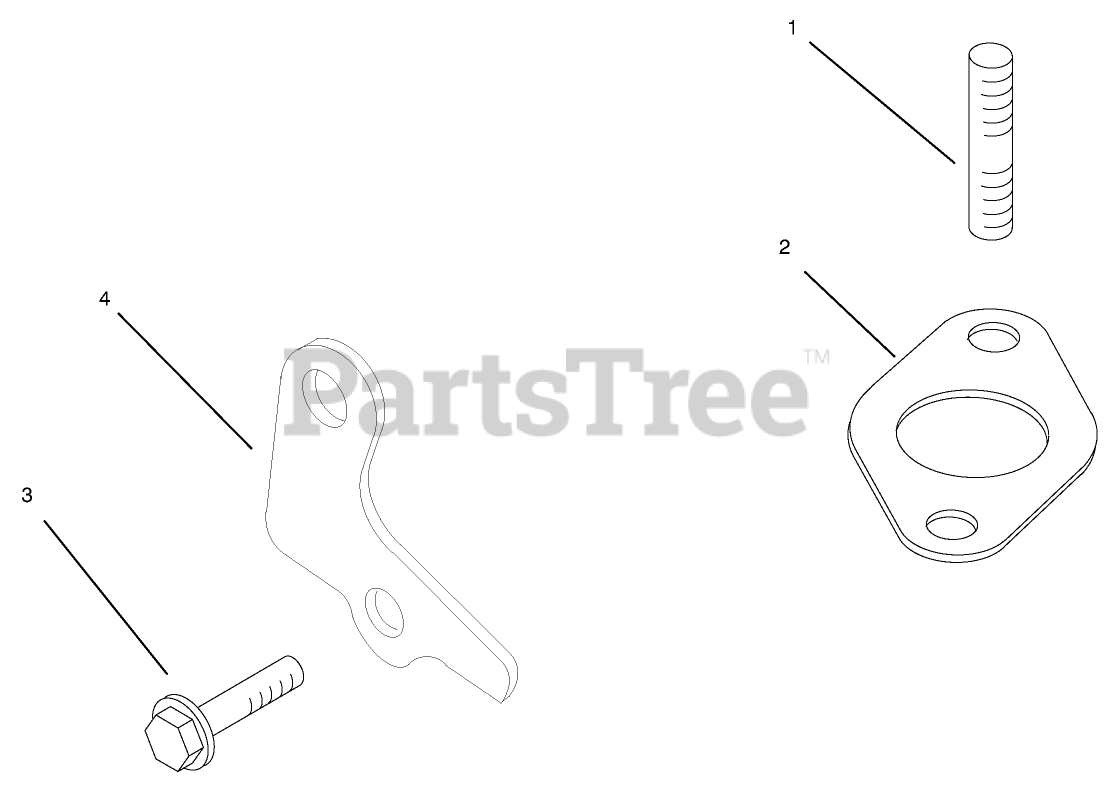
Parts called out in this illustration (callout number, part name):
1	STUD (M8X1.25X33)
2	Gasket-Manifold, Exhaust
3	SCREW-FLANGE, THREAD FORMING (M6X1.0X25)
4	Strap-Lifting
